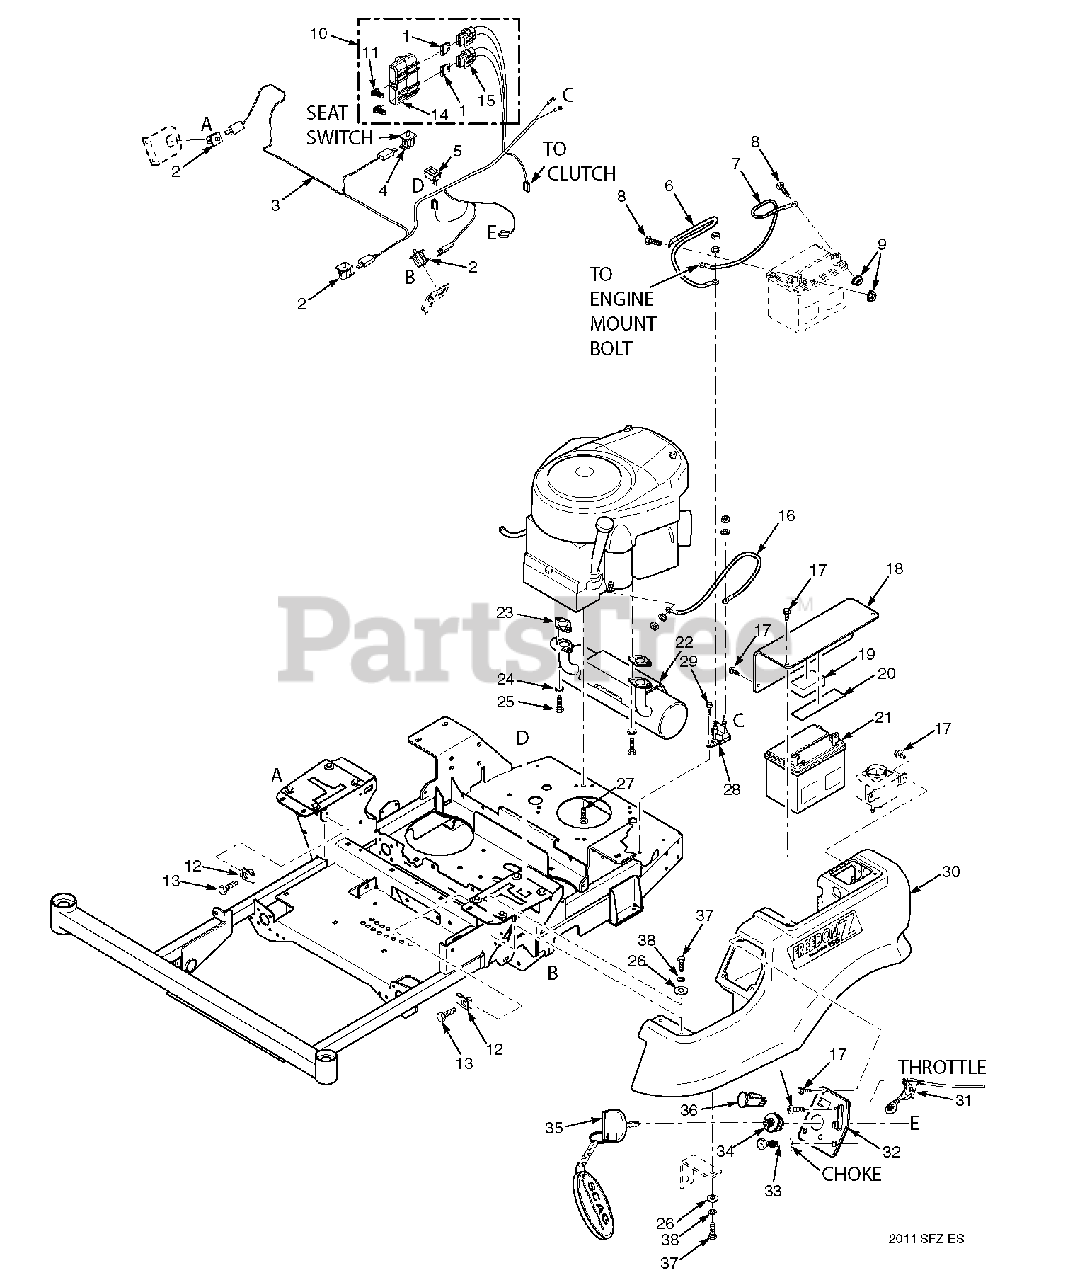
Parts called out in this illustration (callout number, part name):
1	Fuse, 20 amp
2	Switch
3	Wire Harness, Main
4	Switch, Seat
5	Hourmeter
6	Battery Cable, Red 25"
7	Battery Cable, Black 27"
8	Bolt, Hex Head 1/4-20 x 1/2"
9	Nut, 1/4-20
10	Double Fuse Assy.
11	Clip, Wire
12	U-Nut, 3/8-16
13	Bolt, Hex Head 3/8-16 x 1-1/4" Special Lock
14	Cover, Sealed Double
15	Fuse Holder
16	Battery Cable, Red 9"
17	Bolt, Hex Head 1/4-20 x 1/2" Serr. Flange
18	Battery Cover
19	Pad, Battery Hold Down
20	Rubber Pad
21	Battery
22	Muffler
23	Exhaust Gasket
24	Lockwasher
25	Bolt
26	Flatwasher, 5/16-.375 x .875 x .083
27	Bolt, Hex Head 3/8-16 x 1-1/4"
27	Lockwasher, 3/8" Spring
27	Bolt, Hex Head 5/16-18 x 1-1/2"
27	Nut, 5/16-18 Serrated Flange
27	Lockwasher, 5/16" Spring
27	Capscrew, Hex Head 3/8-16 x 1-1/4" Self Tap
28	Solenoid
29	Bolt, Self Tapping 1/2-20 x 3/4" Shakeproof
30	Tank, LH
31	Throttle Cable
32	Instrument Panel w/Decal
33	Choke Cable
34	Ignition Switch
35	Key, Ignition
36	PTO Switch
37	Bolt, Hex Head 5/16-18 x 3/4"
38	Lockwasher, 5/16" Spring
